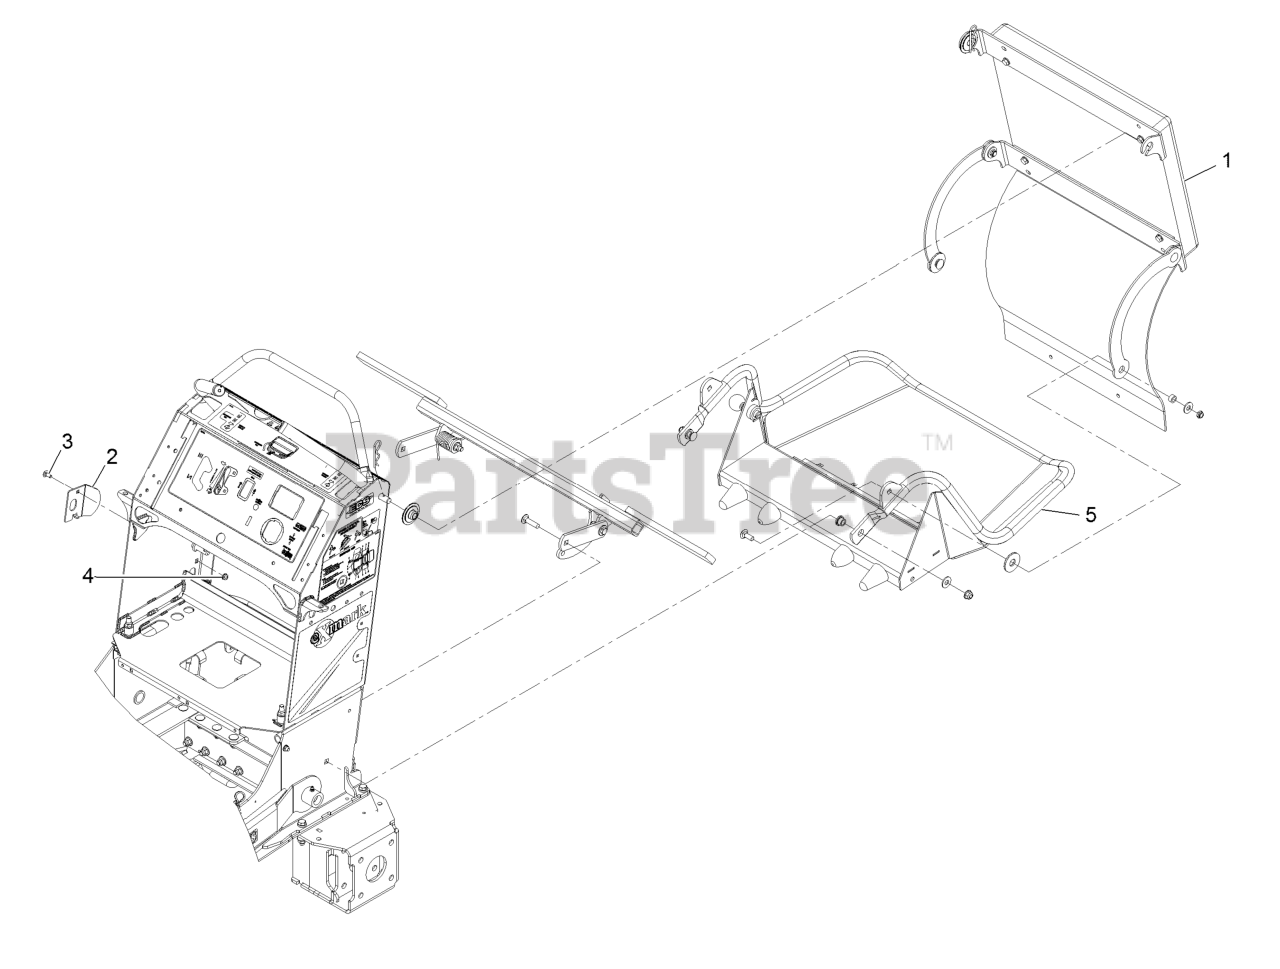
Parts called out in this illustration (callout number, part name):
2	PLATE-STRIKER
3	SCREW-CARR
5	ASM,PLATFORM
